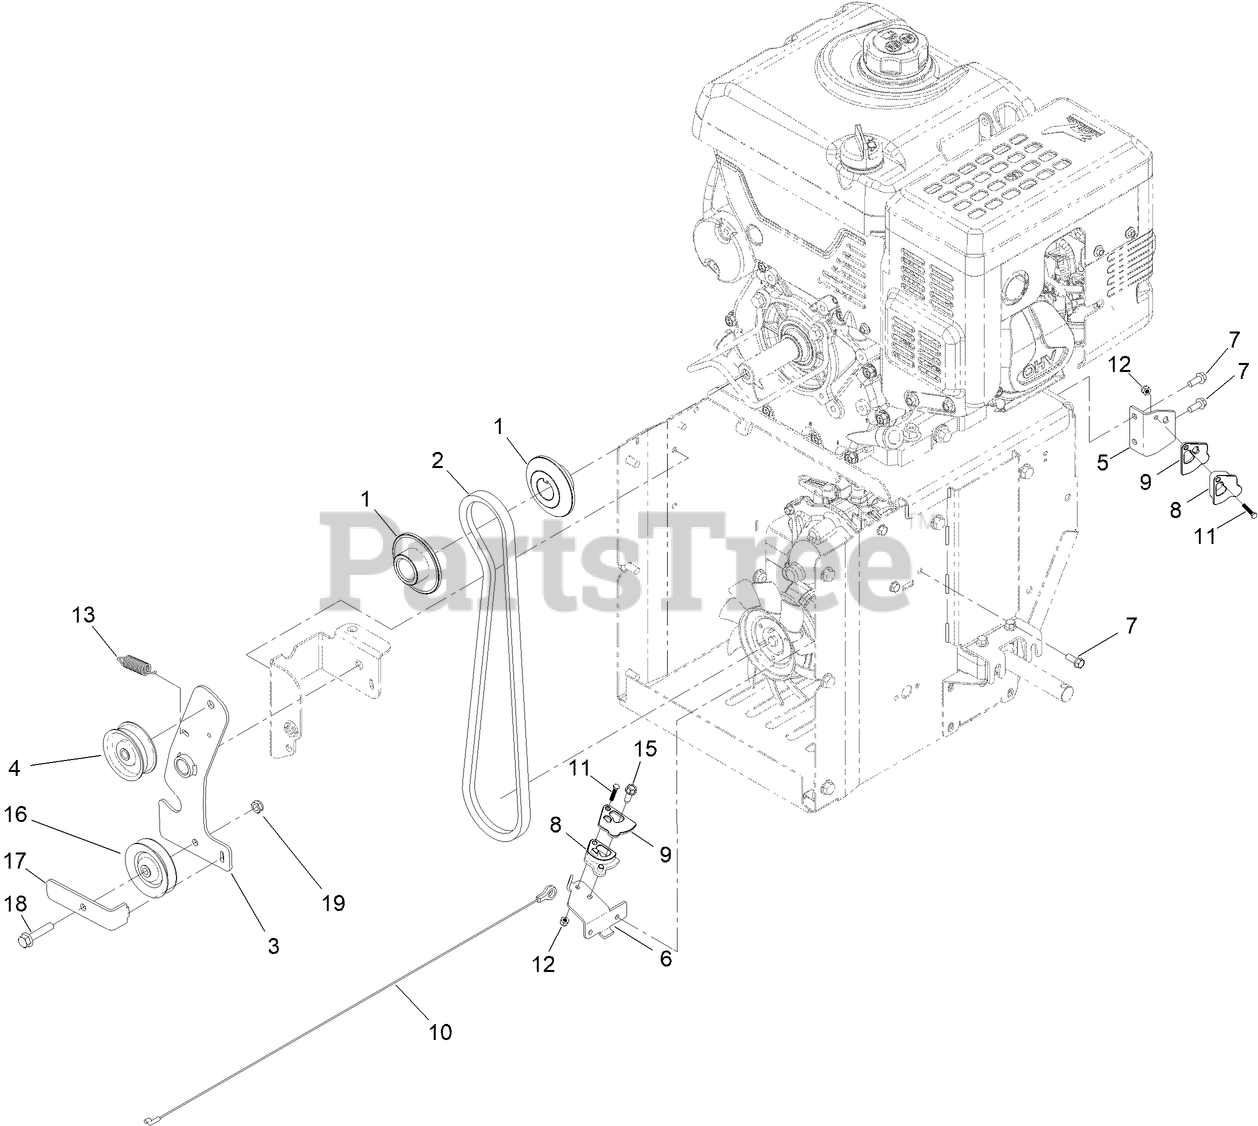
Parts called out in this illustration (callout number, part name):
1	SHEAVE-TRACTION
2	BELT-TRACTION (A, 41.00)
3	ARM-CLUTCH, TRACTION WELD ASM
4	PULLEY-IDLER
5	BRACKET-CABLE
6	ANCHOR-CABLE
7	SCREW-HWH
8	GUIDE-CABLE
9	CAP-GUIDE, CABLE
10	CABLE-TRACTION
11	Screw, Machine, Nozzle, 8-32 x 7/8"
12	NUT-HEX, NYLOCK
13	SPRING-EXTENSION
15	SCREW-HWHTF
16	PULLEY-IDLER
17	GUIDE-BELT
18	SCREW-HHF
19	NUT-HEX
